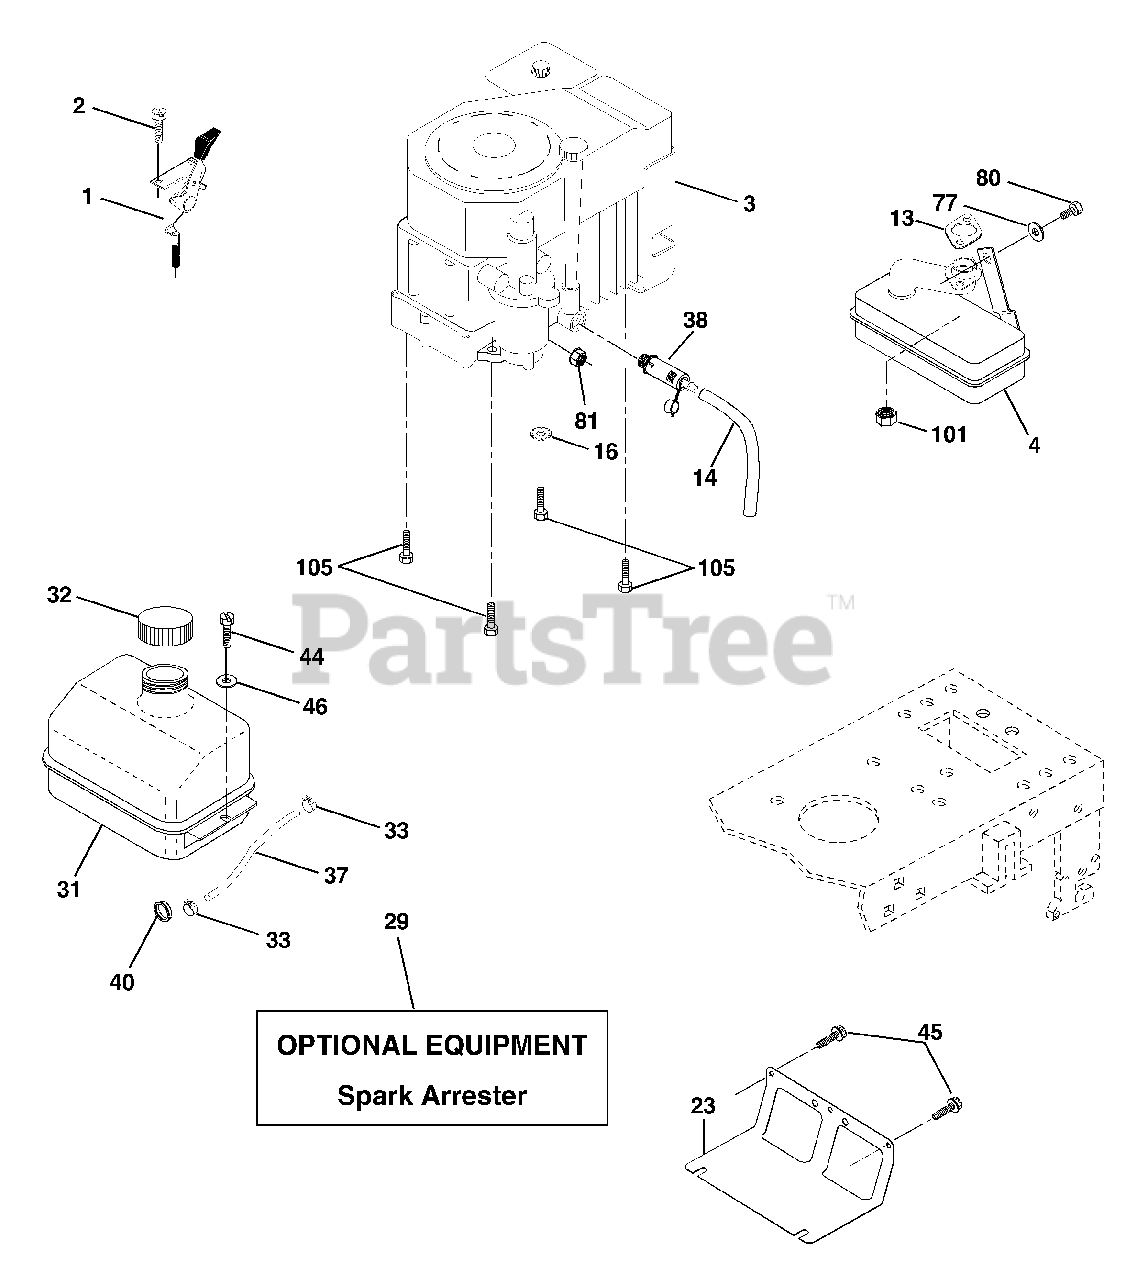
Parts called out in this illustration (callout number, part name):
1	Control Th/ch Flag
2	Screw Hex Thd Cut 1/4-20 x 1/2
13	Gasket Eng
14	Tube Drain Oil Easy
16	Washer Lock Ext Tooth 3/8
23	Shield Brn/Dbr Guard
29	Kit Spark Arrestor (Flat Scrn)
31	Tank Fuel Front
32	Cap Asm Fuel W/sym Vented
33	Clamp Hose Black
37	Line Fuel 20"
38	Plug Drain Oil Easy
40	Bushing Snap Nyl Blk Fuel Line
44	Screw Hexwsh Thdrol 1/4-20 x 3/4
45	Screw Hexwsh Thdr 3/8-16 x 3/4
46	Washer 9/32 x 7/8 x 16 Ga
77	Washer 5/16x 3/4 x 16 Ga.
80	Bolt Hex Hd 5/16-18 x 1/2
81	Nut Keps Hex 1/4-20 Unc
101	Nut Flange M8 1.25 N/LK Zinc
105	Screw 3/8-16 x 1
